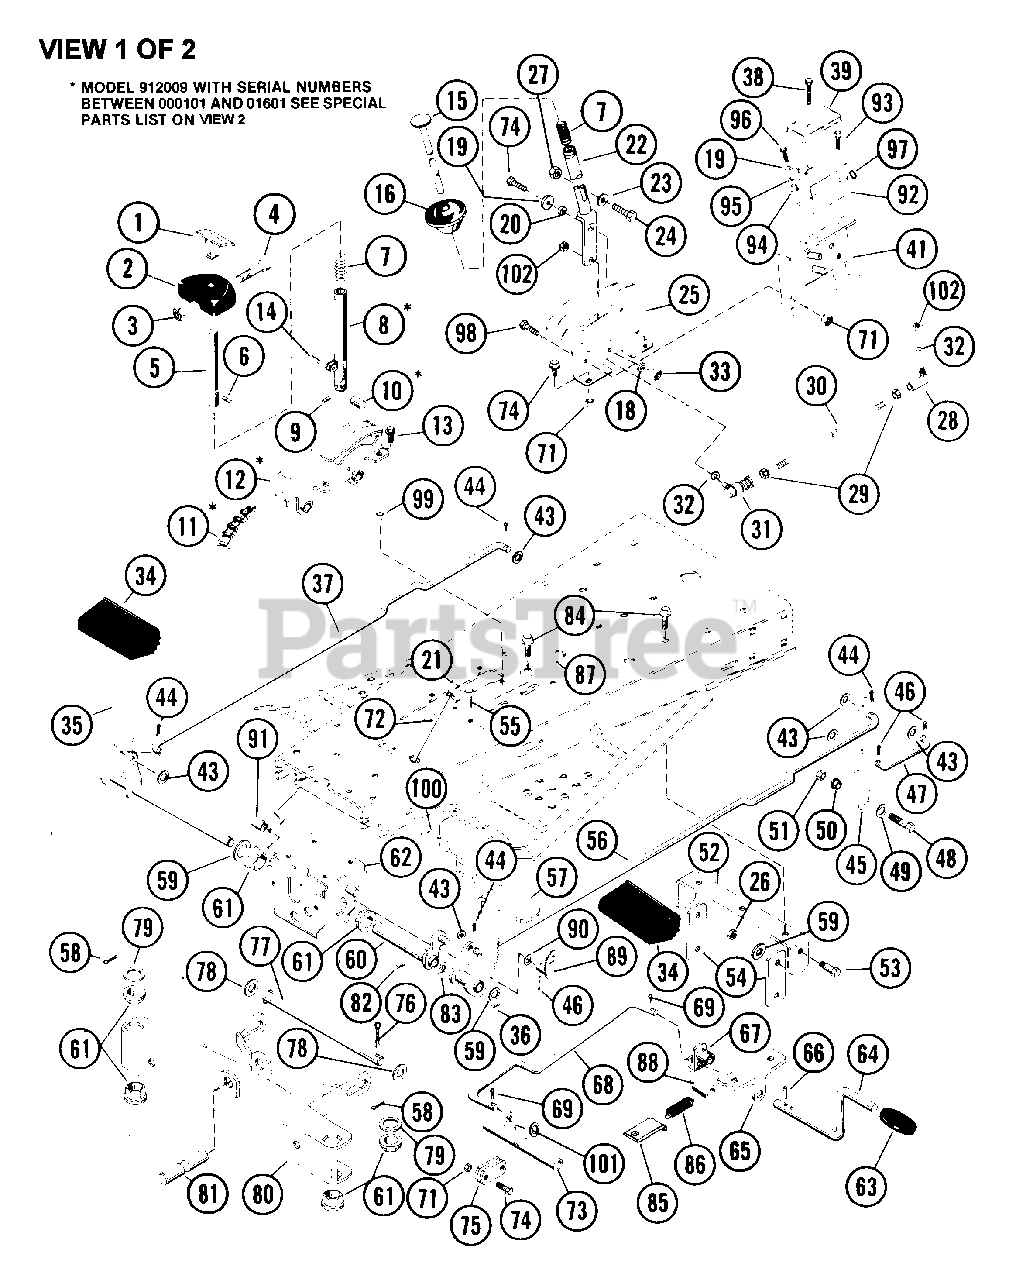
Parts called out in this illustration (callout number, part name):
1	T PLUNGER
2	T HANDLE
3	NUT-LK TOP 10-24 PL
4	BLT-HEX 10-24X1.25 FHPL
6	PIN-ROLL .250X1.25
7	SG-COMP ??X.44X?? WLD 10
8	MOWER LIFT ARM
9	PIN-ROLL .125X.75
11	ROLLER CHAIN
12	MOWER HEIGHT QUAD
13	BLT-HEX .25-20X.50 PL GR2
14	PIN-ROLL .156X.75
15	SHIFT RELEASE HANDLE
16	SHIFT BALL
17	BLT-HEX .31-18X1.00 PL GR 2
18	WSHR-LK .312X.097 PL HVY
19	WSHR-FL-STL .38X.875X.083 PL
20	SPACER BUSHING .5 X .32 X .21
22	SHIFT LEVER
23	WSHR-FL-STL .281X1.250X.048PL
24	BLT-HEX .25-20X1.25
25	SHIFT CONTROL SEGMENT
26	NUT-LK-JAM-CTR .375-16 PL
27	NUT-LK TOP .250-20 PL
28	BALL JOINT
29	NUT-HEX .312-24 PL
30	SHIFT LINK
31	SNAP IN BALL JOINT
32	WSHR-LK .312X.097 PL HVY
33	NUT-HEX .312-18
34	PEDAL COVER
35	BRAKE LEVER
36	PIN-ROLL .125X1.00
37	BRAKE ROD
38	SCR-TAP 12-14X1.25 CROVH PL 1A
41	SWITCH BRACKET
43	WSHR-FL-STL .382X.812X.023 PL
44	PIN-COTR .09X.75 PL
45	CLUTCH LINK BAR
46	PIN-COTR .12X1.0 PL
47	CLUTCH LINKAGE ROD
48	BLT-HEX .38-16X.75 PL GR2
49	WSHR-FL-STL .630X1.005X.062 PL
50	SHOULDER SPACER
51	NUT-LK-CTR .375-16 GR A PL
52	HANGER BRACKET
53	SHOULDER BOLT .50 X .31
54	HANGER LINK
55	BLT-SERHFWH .25-20X.50 PL
56	CLUTCH ROD
57	CLUTCH BRAKE LEVER
58	PIN-COTR .12 X 1.25 PL
59	WSHR-FL-STL .505X.875X.024 PL
60	CLUTCH BRAKE LEVER
61	FLANGE BUSHING
62	AXLE SUPPORT
64	MOWER CLUTCH PEDAL
65	MOWER CLUTCH BRACKET
66	PIN-ROLL .188X1.00
67	OVER CENTER LEVER
68	MOWER CLUTCH LINK
69	PIN-COTR .09X.75 PL
71	NUT-LK .312-18 GR A PL
72	PARKING BRAKE ROD
73	MOWER CLUTCH LEVER
74	BLT-HEX .31-18X.75 PL GR2
75	FRONT LINK
76	PIN-COTR .12X1.0 PL
77	HANGER PIN
78	WSHR-FL-STL .531X1.062X.095 PL
79	WSHR-FL-STL .755X1.375X.062 PL
80	FRONT AXLE
81	AXLE PIVOT PIN
82	PIN-ROLL .188X.88
83	WAVE WASHER .531X.781X.125FH
84	BLT-SCRHFWH .38-16X.50 PL
85	SPRING CLIP
86	SG-TENS .062X.437X.312 WLD 12
87	GUIDE PLATE
89	BRAKE LATCH
90	WSHR-FL-STL .511X1.441X.125 PL
91	BRAKE RELEASE LEVER
92	SWITCH HOUSING
93	SCR-TAP 10-24X.375 CRPH 1A
94	BSHG, FLG .325X.499X.26X.88
95	CAM NO SCRAP
96	BLT-SERHFWH .31-18X.75 PL
97	GROMMET, .31 ID
98	BLT-HEX .31-18X.50 PL GR2
99	NUT-LK-CTR .250-20 PL
100	SWITCH BRACKET
101	WSHR-FL-STL .380X.626X.033
102	NUT-LK .312-24
103	MOWER LIFT ARM
104	PIN
105	MOWER HEIGHT QUADRANT
106	CHAIN ROLLER
107	PAN HEIGHT BRACKET
108	ROLLER CHAIN
